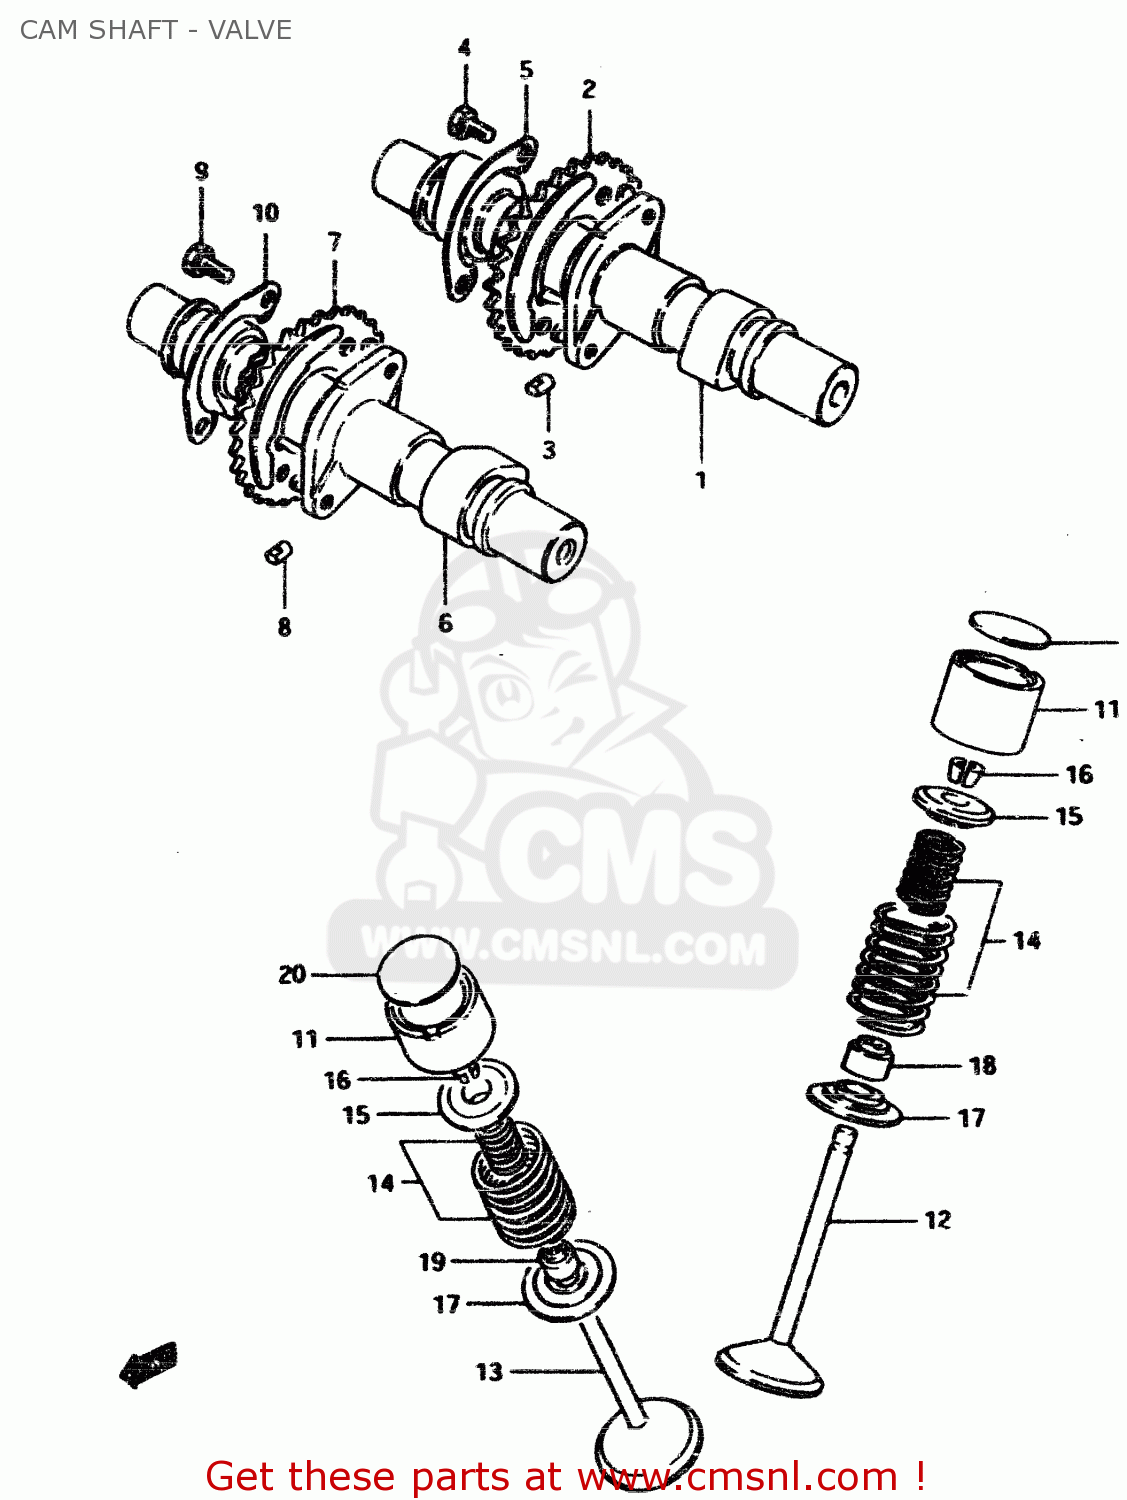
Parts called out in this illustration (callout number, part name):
1	CAMSHAFT,INTAKE
2	SPROCKET,CAMSHAFT
3	PIN,SPROCKET
4	BOLT(6X12.5)
5	WASHER,CAM CHAIN SPROCKET
6	CAMSHAFT,EXHAUST
7	SPROCKET,EXHAUST CAM(NT:30)
8	PIN,SPROCKET
9	BOLT(6X12.5)
10	WASHER,CAM CHAIN SPROCKET
11	TAPPET
12	VALVE,INTAKE
13	VALVE,EXHAUST
14	SPRING SET,VALVE
15	RETAINER,VALVE SPRING
16	COTTER VALVE
17	SEAT,VALVE SPRING
18	SEAL,OIL(7X14.4X9)
19	SEAL,OIL(7X14.5X10.5)
20	SHIM,TAPPET
